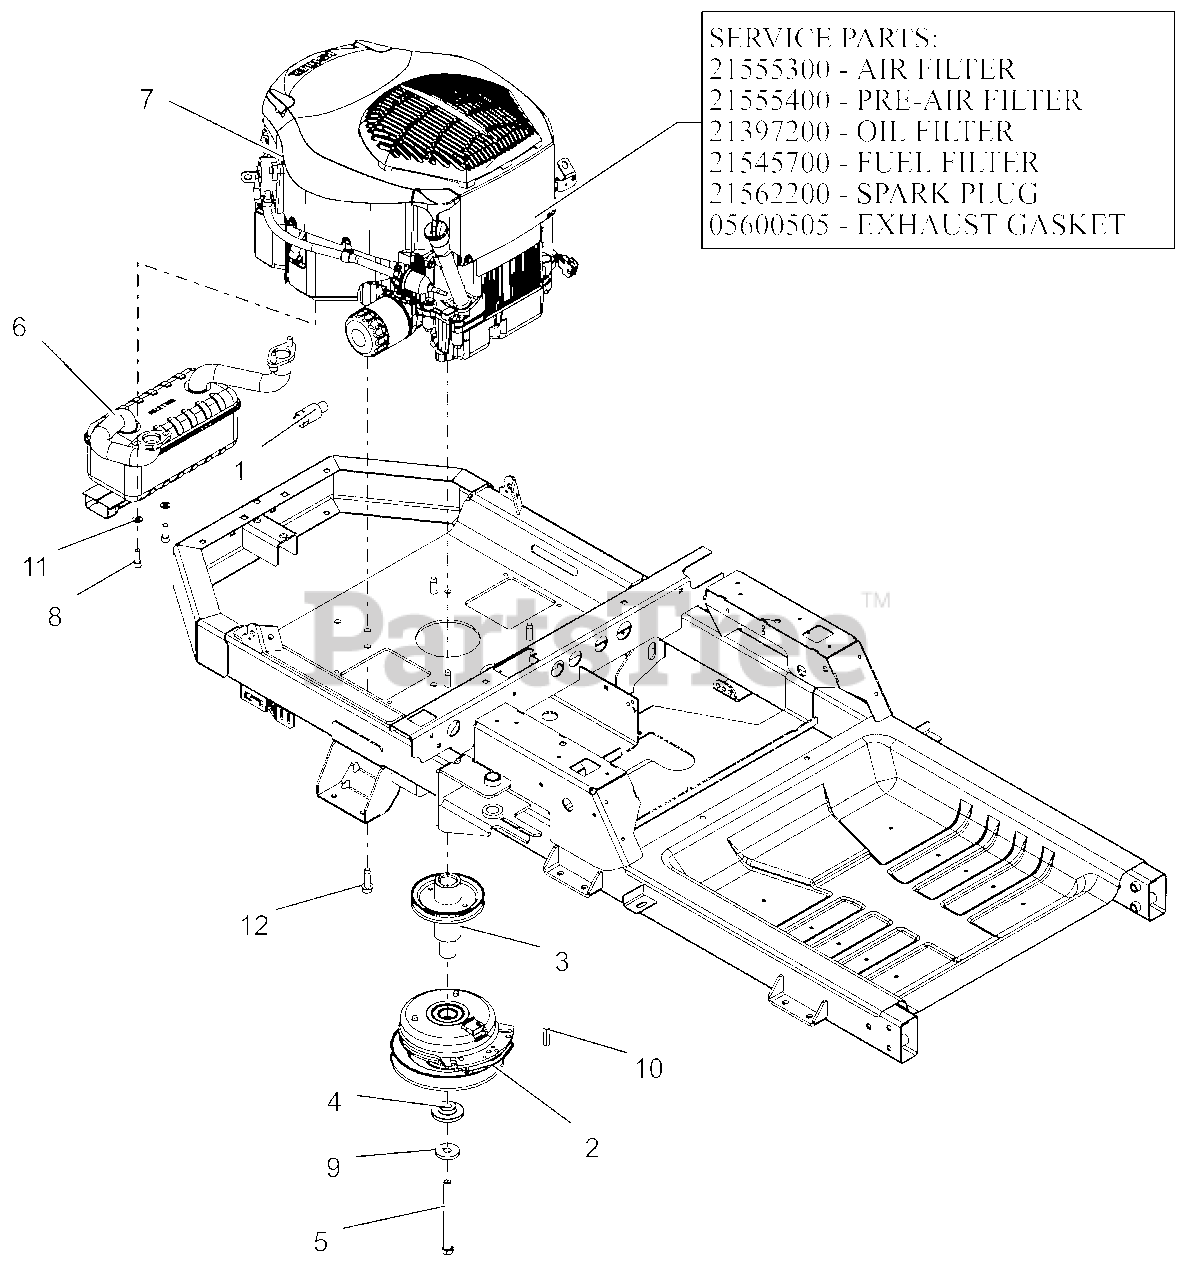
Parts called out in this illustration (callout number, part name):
1	DRAIN, OIL
2	CLUTCH,105FTLB MONOPOLE 6.83"
3	WLDMT, DRIVE SHEAVE (LG XL)CZC
4	BSHG-FLG .469X1.06X.574X2.0
5	BLT-HEX.438-20X5 GR8 YZ NYTORQ
6	MUFFLER, KOHLER
7	ENGINE, KOHLER 26 HP PRO W/SC
7	AIR FILTER, KOHLER
7	PRE CLEANER, KOHLER
7	FILTER, OIL - KOH CV20
7	FILTER-FUEL KOHLER COURAGE PRO
7	PLUG, SPARK (RFI)
7	GASKET, MUFFLER KOHLER TWIN
8	SCR, SKH .312-18X.875 GR8 ZCC
9	WASHER, 7/16" SPRING DISK
10	KEY-SQ .25 X 1.25 X .25 SAE
11	WSHR,LK-REG .312X.078 ZCC
12	SCR,TAP .375-16X1.25HWH TR ZCC
